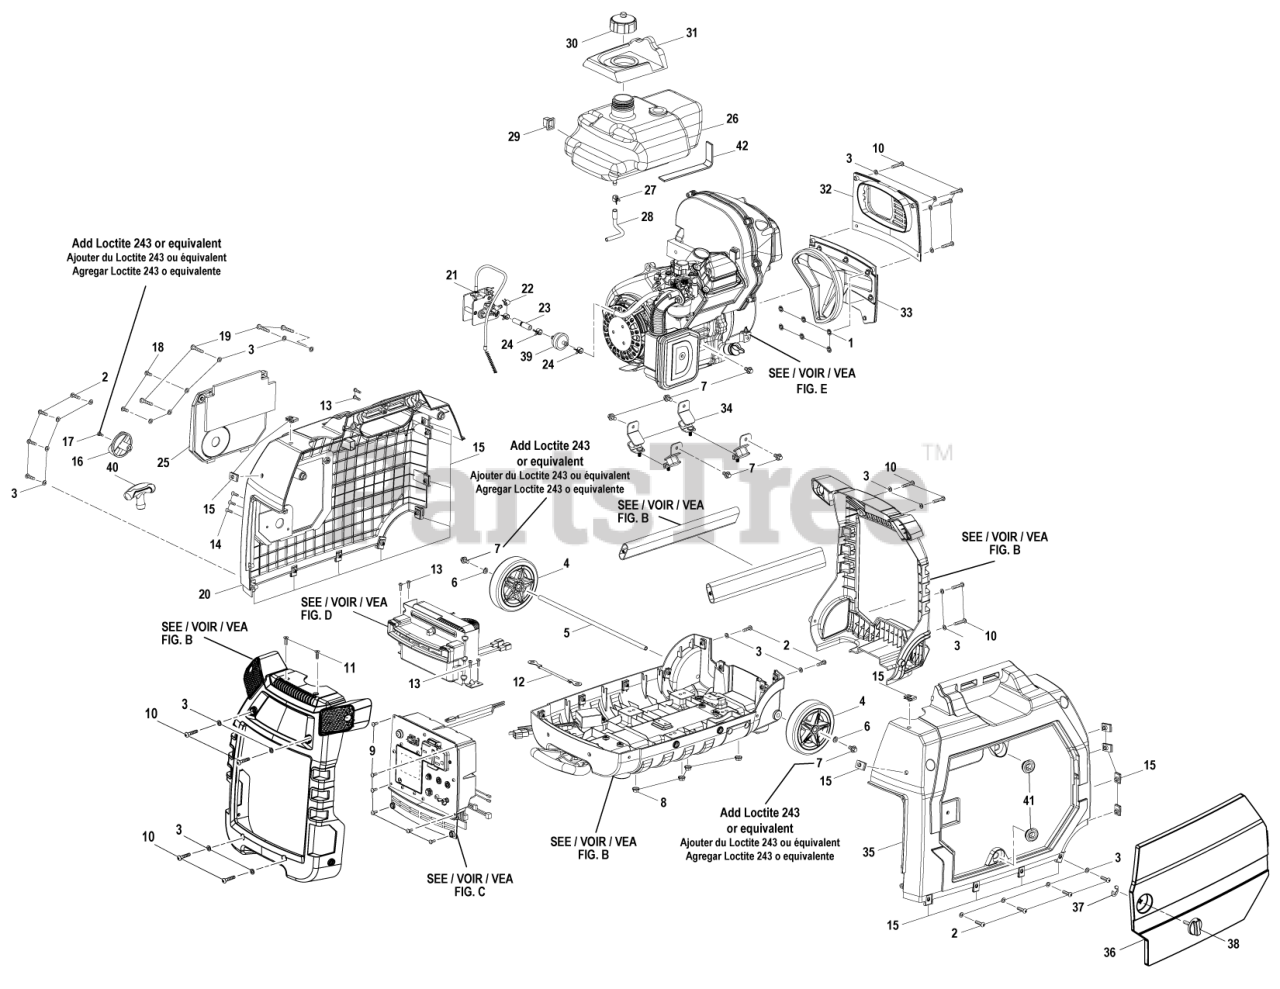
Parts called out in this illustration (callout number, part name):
1	RETAINER, INTERNAL TOOTH
6	WASHER, LOCK
8	NUT, LOCK
9	SCREW W/WASHER
12	WIRE, GROUND
16	KNOB, CONTROL
20	ASSY., LEFT HOUSING
21	VALVE, FUEL SHUT OFF
22	CLAMP, FUEL HOSE
23	HOSE, FUEL
24	CLAMP, FUEL HOSE
25	ASSY., STARTER COVER
26	ASSY., FUEL TANK
28	HOSE, FUEL
29	SUPPORT, FUEL TANK
30	CAP, VENTED FUEL
31	GUARD, OVERSPILL
32	Upper Exhaust Panel
33	ASSY., LOWER EXHAUST PANEL
34	MOUNT, ENGINE (45 DEGREE)
35	ASSY., RIGHT HOUSING
36	ASSY., MAINTENANCE COVER
38	KNOB, LOCK
39	FILTER, FUEL
40	HANDLE, RECOIL
42	RUBBER PAD
